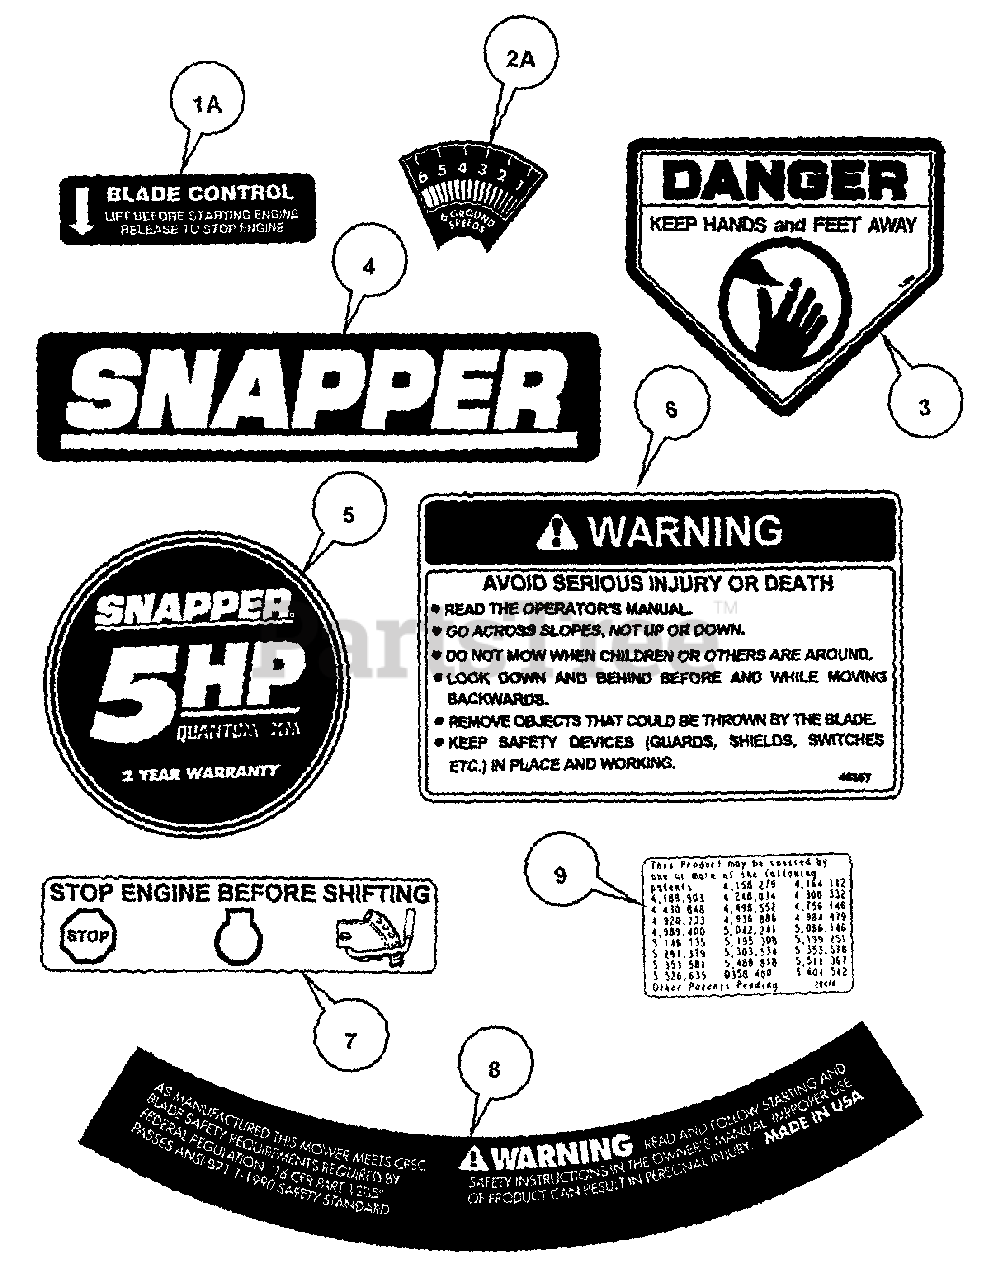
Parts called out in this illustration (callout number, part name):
1A	DECAL, Blade Control
2A	DECAL, Speed Sector (Self-Propelled)
3	DECAL, Danger
4	DECAL, Snapper
5	DECAL, SNAPPER 3.87 Dia. (Push)
6	DECAL, Warning
7	DECAL, Shift Warning (Self-Propelled)
8	DECAL, Deck Warning
9	DECAL, Patent Numbers
